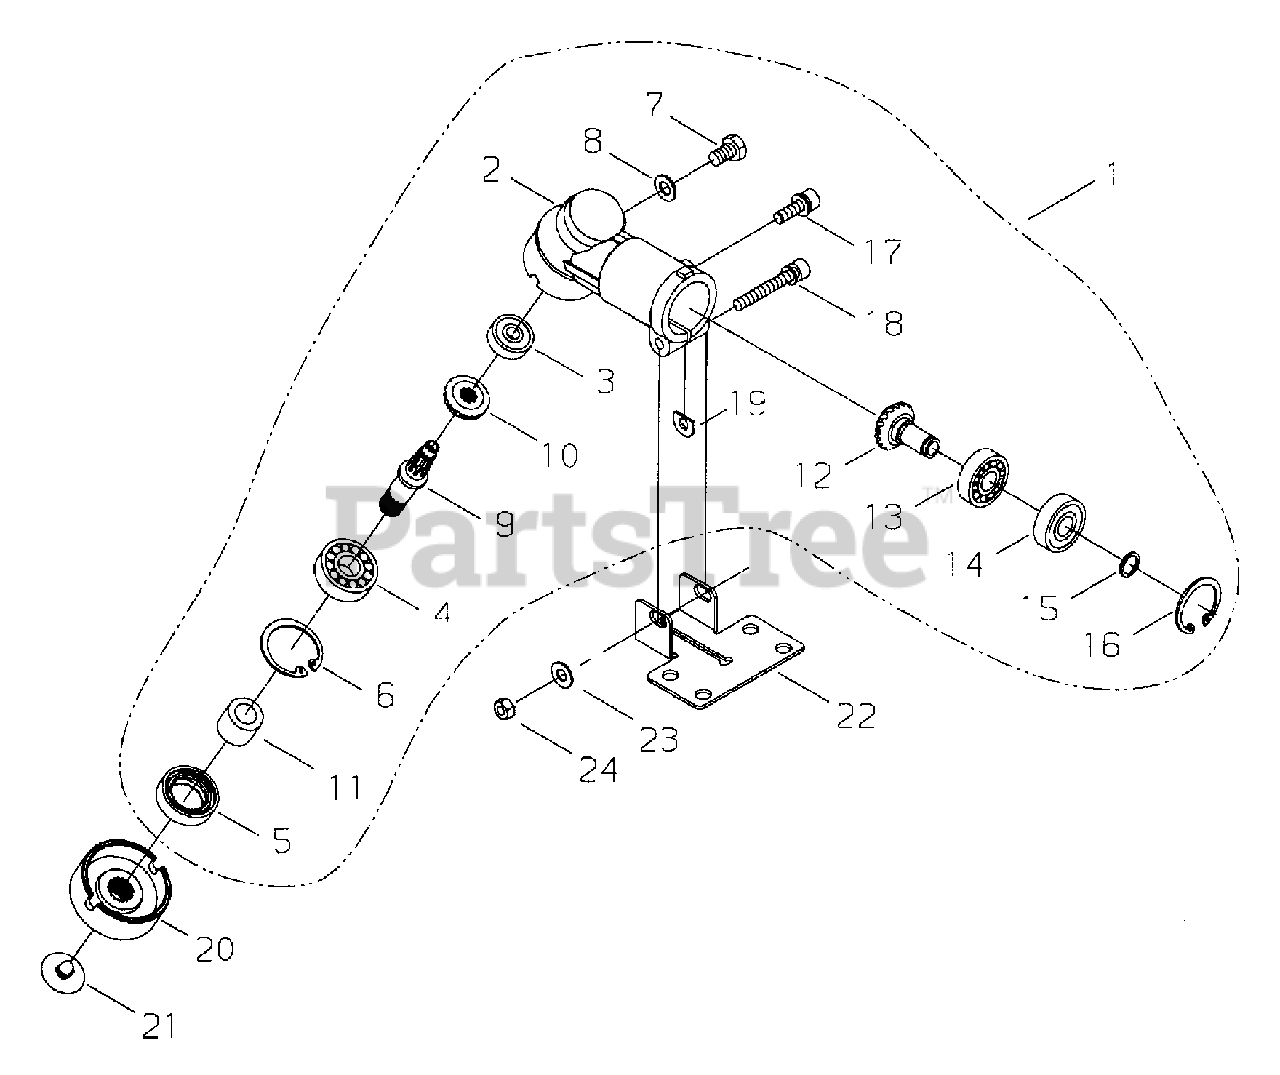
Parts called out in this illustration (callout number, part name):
1	GEAR CASE ASSY
2	HOUSING, GEAR CASE
3	BEARING, BALL 626 DDU
4	BEARING, BALL 6000
5	SEAL, OIL
6	RING, SNAP Ø26
7	BOLT M6×10
8	WASHER
9	SHAFT, GEAR
10	GEAR, BEVEL
11	SPACER
12	GEAR, PINION
13	BEARING, BALL 608
14	BEARING, BALL 608ZZ
15	RING, SNAP
16	RING, SNAP Ø22
17	BOLT M5×16
18	BOLT M5×35
19	D-WASHER
20	HOLDER
21	CLIP
22	PLATE, SHIELD MOUNTING
23	WASHER 5 MM
24	NUT M5
